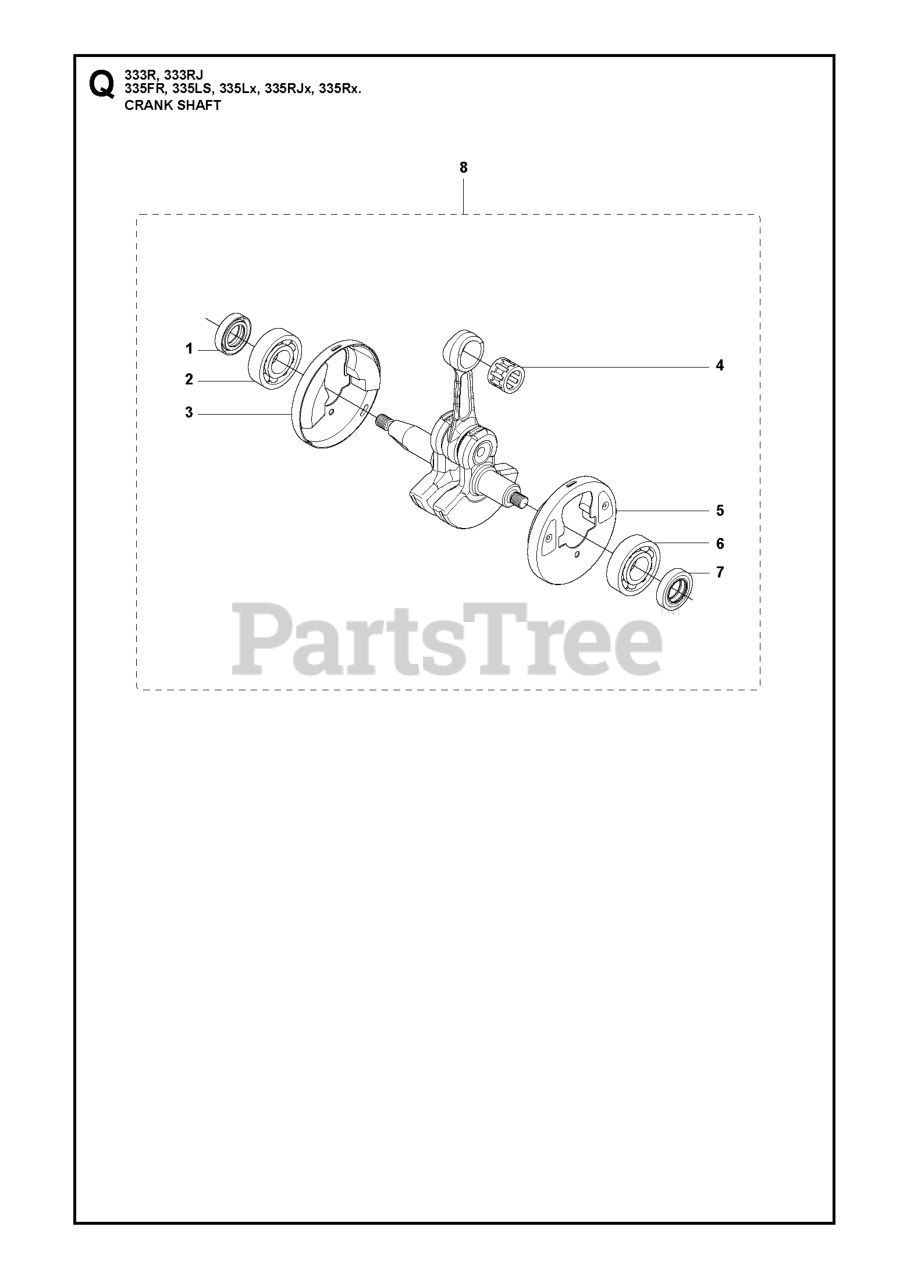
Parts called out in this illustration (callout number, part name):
1	SEALING RING
2	BALL BEARING
4	SUPPORT BUSHING
6	BALL BEARING
7	SEALING RING
8	CRANKSHAFT
